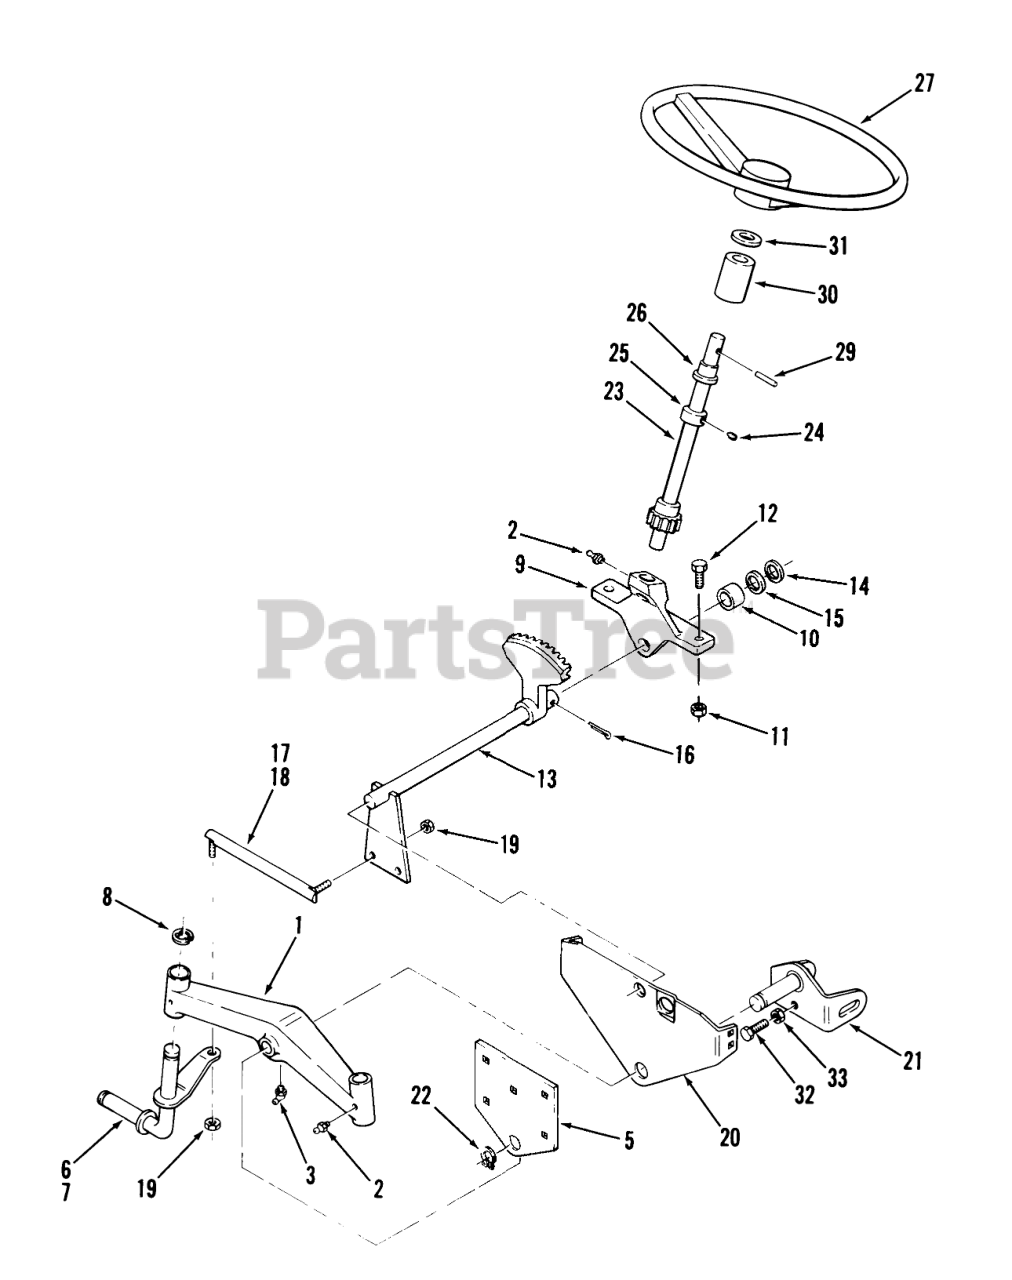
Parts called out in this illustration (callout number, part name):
1	AXLE-FRONT R
2	Zerk
3	FITTING-GREASE
5	PLATE-FRONT AXLE R
6	Assy-Front Spdl RH
7	Assy-Front Spdl LH
8	Snap Ring
9	Support
10	BEARING-BRONZE
11	Nut
12	BOLT
13	ASSY-STRG SHFT LO R
14	WASHER-SHIM
15	WASHER
16	PIN-4
17	25LL JOINT ASSY R R
18	BALL JOINT ASSY L R
19	NUT-6
20	Support Front Axle
21	Front Hanger (Mower)
22	Snap Ring
23	ASSY-STEER SHFT U R
24	SCREW-SET
25	Collar
26	BEARING
27	STEERING WH 13" PLAS
29	Pin-Roll
30	Collar
31	WASHER-BOWED
32	SCREW-HH
33	Nut
